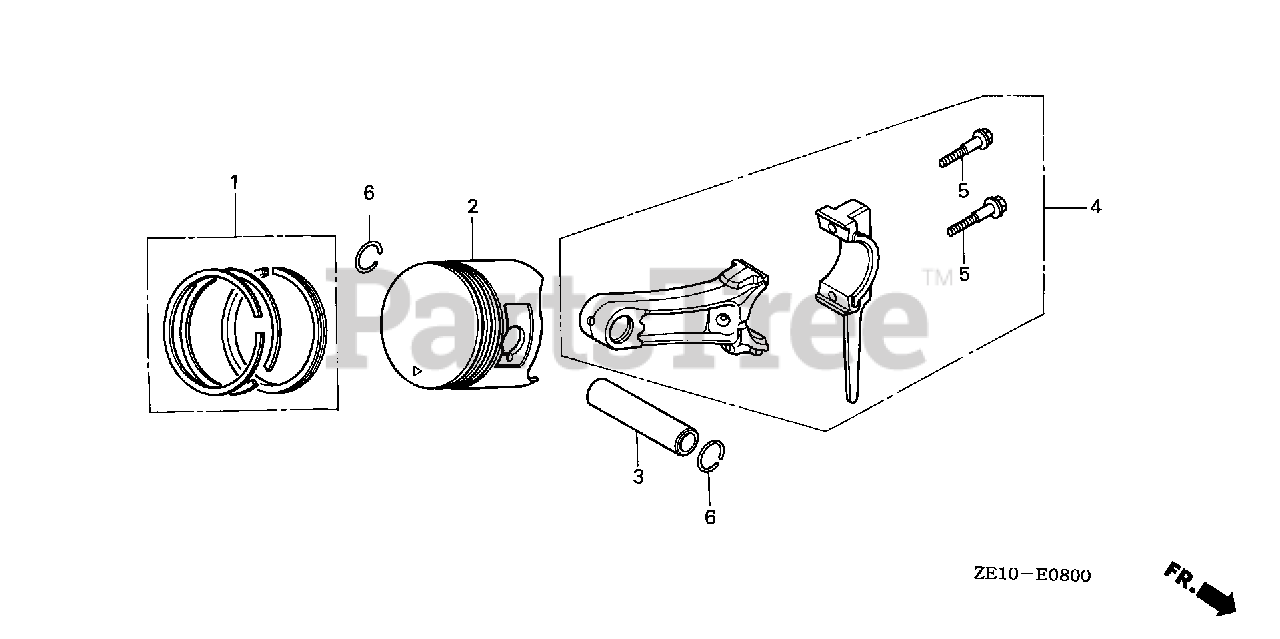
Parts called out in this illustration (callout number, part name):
1	RING SET, PISTON (STD) (NIPPON)
1	RING SET, PISTON (STD) (TEIKOKU)
1	RING SET, PISTON (0.25) Use up to Engine SN 2120317.
1	RING SET, PISTON (0.50) Use up to Engine SN 2120317.
1	RING SET, PISTON (0.75) Use up to Engine SN 2120317.
1	RING SET, PISTON (0.25)
1	RING SET, PISTON (0.50)
1	RING SET, PISTON (0.75)
2	PISTON (STD)
2	PISTON (0.25)
2	PISTON (0.50)
2	PISTON (0.75) Use up to Engine SN 2120317.
2	PISTON (0.75) Use from Engine SN 2120318.
3	PIN, PISTON
4	ROD ASSY., CONNECTING
4	ROD ASSY., CONNECTING (STD)
5	BOLT, CONNECTING ROD
6	CLIP, PISTON PIN (18MM)
